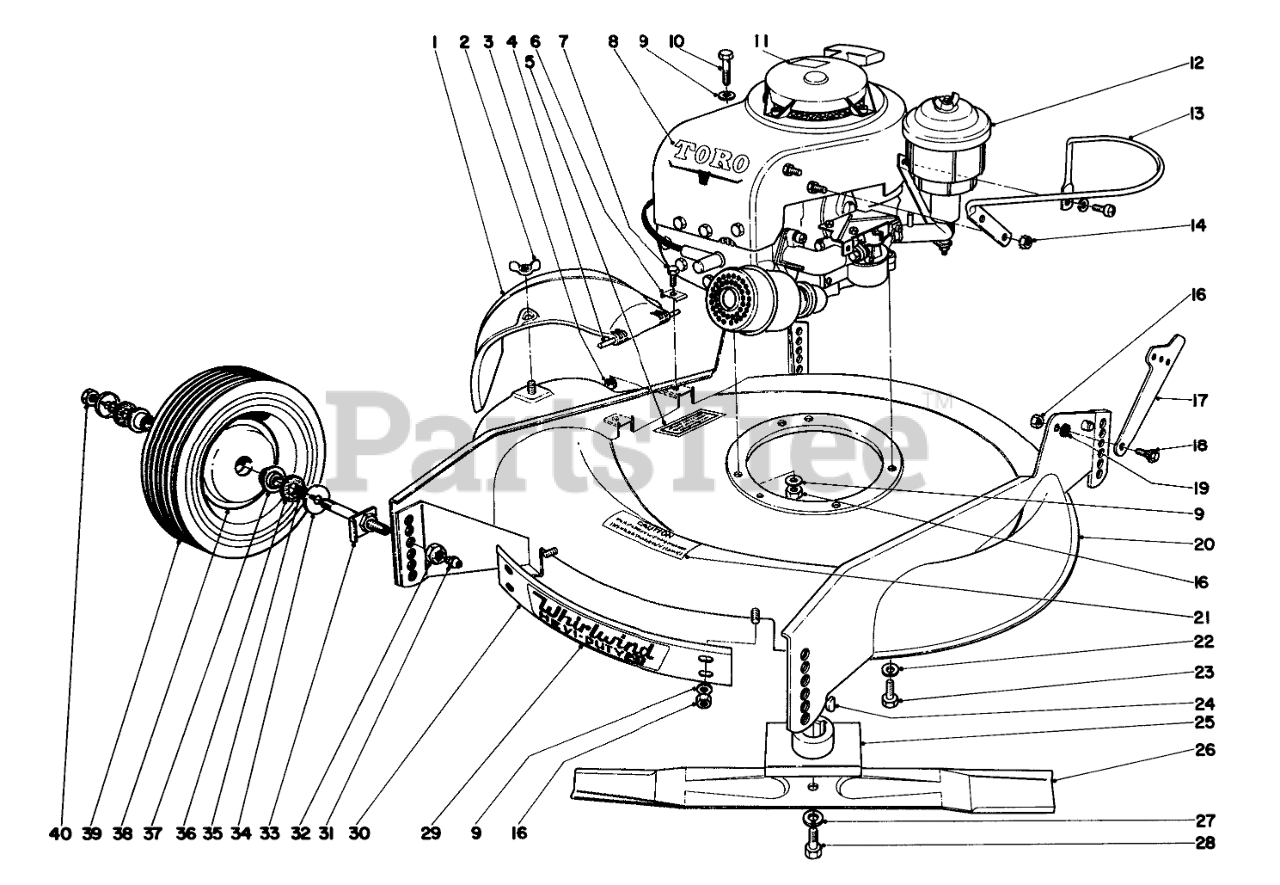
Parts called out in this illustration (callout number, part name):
1	Deflector
2	Wing Nut
3	Nut
4	HINGE PIN
5	Decal
6	Clamp
7	SCREW-HH
8	Decal
9	WASHER-PLAIN
10	SCREW-HH
11	Decal
12	Engine
14	NUT-KEPS
16	Nut
17	Latch
18	SCREW-SHOULDER
19	SPACER
20	Housing
21	Decal
22	WASHER-LOCK
23	SCREW-HH
24	KEY-WOODRUFF
25	BLADE RETAINER WA
26	Blade
27	WASHER-LOCK
28	SPECIAL SCREW
29	Decal
30	Guard
31	FITTING-GREASE
32	NUT-LOCK, NI
33	Spindle Ass-y. (Incl. Ref. #29)
34	SLINGER
35	O-RING
36	Washer
37	BEARING-BALL
38	Wheel Ass-y. w/Tire (Inc. Ref. #37 & 39)
39	1.75-8 SEMIPNEU TIRE
40	Nut
